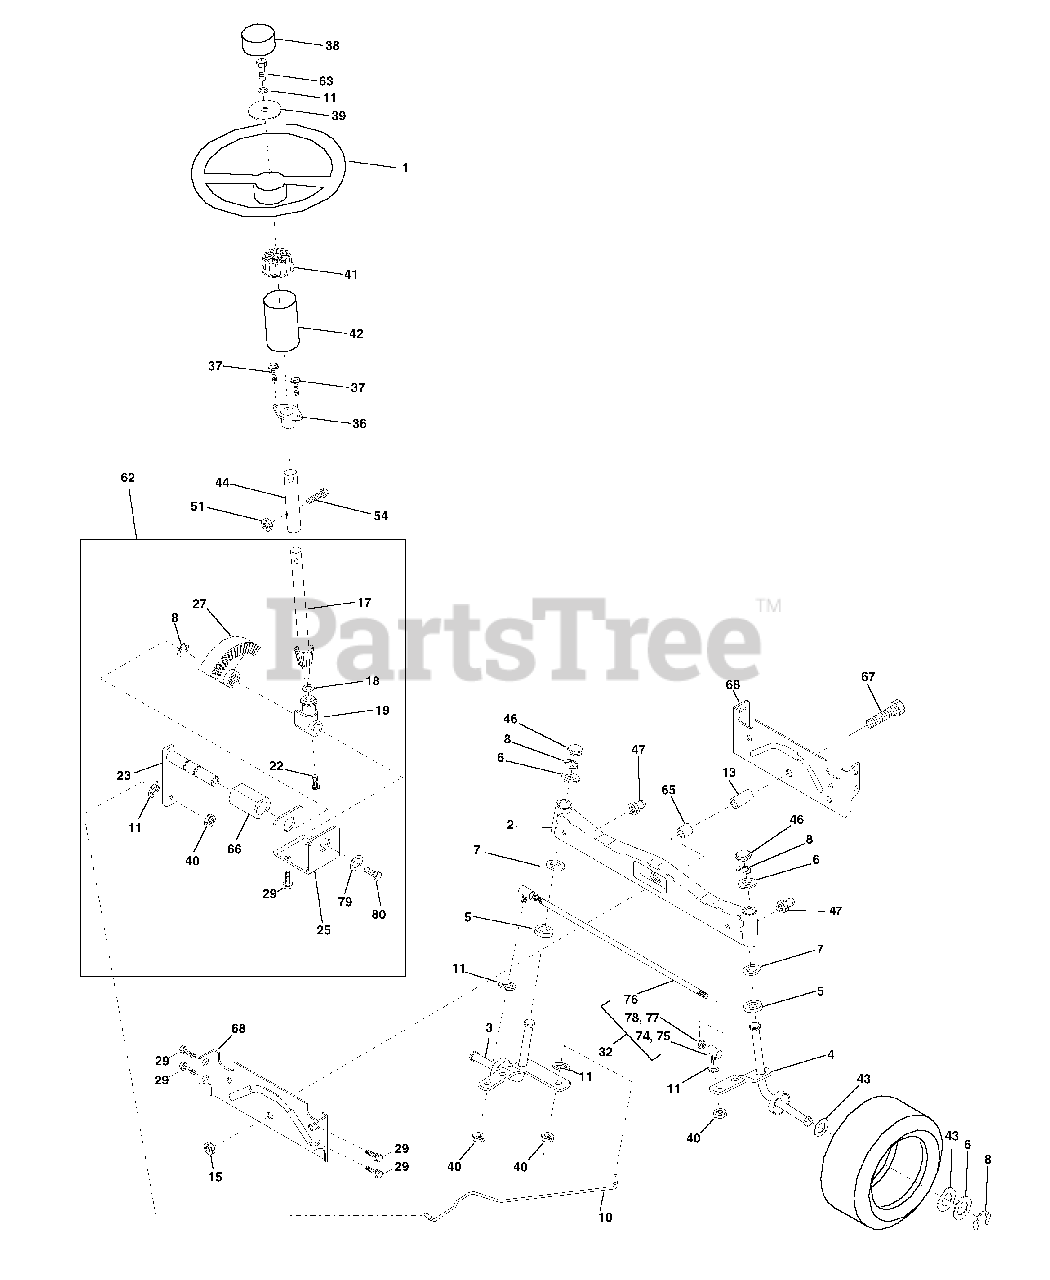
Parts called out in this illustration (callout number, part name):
1	Wheel Steering
2	Axle Front Casting Machined
3	Spindle Asm LH Cast 15"
4	Spindle Asm RH Cast 15"
5	Bearing Race Thrust Harden
6	Washer 25/32 X 1-5/8 X 16 Ga
7	Washer 27/32 X 1-1/4 X 16 Ga
8	Ring Klip #t5304-75
10	Link Drag Extended Cast
11	Washer Lock Hvy Hlcl Spr 3/8
13	Bearing Axle STLT/GT
15	Nut Lock Flange 5/8-11 Unc
17	Shaft Asm Strg
18	Washer Thrust 515x 750x 033
19	Support Shaft
22	Screw Hex Wsh Hd Torx
23	Shaft Asm Pittman
25	Bracket Steering
27	Gear Sector
29	Screw Thdrol 3/8-16x3/4 Ty-tt
32	Rod Asm Tie Ball J Adj VGT
36	Bushing Strg
38	Insert Cap Strg Wh Au
39	Washer 13/32 X 2-3/8 X 8 Ga
40	Lock nut
41	Adaptor Wheel Strg
42	Boot Steering Shaft
43	Washer 25/32 X 1 1/4 X 16 Ga
44	Extension Steering Shaft LR/LT
46	Cap Spindle Fr Top Blk
47	Fitting Grease
51	Nut Lock Hex w/Ins 5/16-18
54	Bolt Fin Hex 5/16-18 Unc x 1-1/4
62	Kit, Steering Assembly Svc
63	Bolt Fin Hex 3/8-16unc x 1 Gr. 5
65	Spacer Axle
66	Bearing Arm Pittman
67	Bolt, Fin Hex 5/8-11 UNC x 2-3/4
68	Axle, Brace
74	Joint Asm Ball Rh
75	Joint Asm Ball Lh
76	Rod Tie Ball J Adj
77	Nut Hex Jam 3/8-24 Unf Lh
78	Nut Hex Jam 3/8-24 Unf
79	Washer 13/32 x 1-1/4 x 12
80	Bolt Hex Nylon 3/8-16 x 3/4
